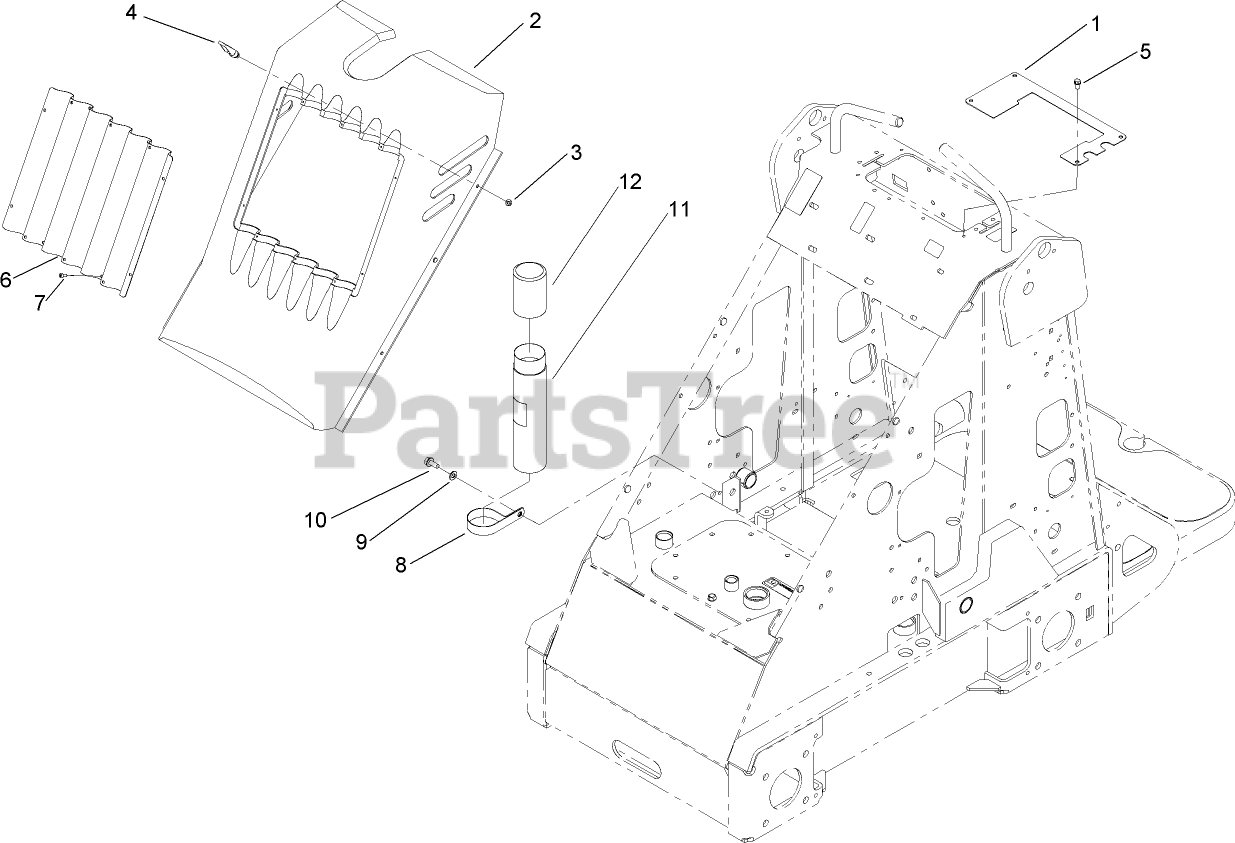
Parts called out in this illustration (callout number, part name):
1	PLATE-COVER
2	COVER-HOOD
3	WASHER
4	LATCH-SWELL
5	SCREW-HWH
6	GRILLE-SCREEN
7	SCREW-PPH
8	CLAMP-R
9	WASHER-PLAIN
10	SCREW-HWHTF
11	TUBE-MANUAL
12	CAP-HOUSING
